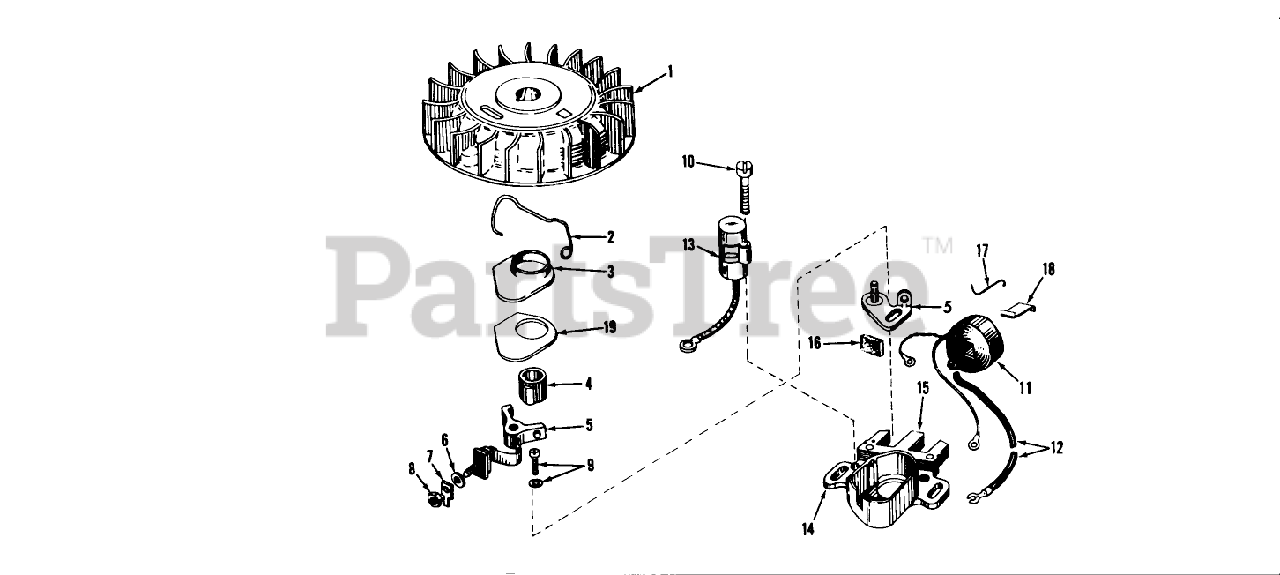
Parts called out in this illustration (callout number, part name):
1	Flywheel
2	Spring Breaker Box
3	Cover, Dust
4	Cam, Breaker
5	Breaker Assy.
6	Washer
7	Terminal
8	DECAL
9	Breaker Screw
10	Condenser Screw
11	Coil Assy., (Inc. Ref. Nos. 12, 13 18)
12	Wire, Lead
13	Condenser
14	Core Plate
15	Stator Assy., (Incl. Nos. 2, 3, 5 thru 14 16 thru 19)
16	Felt,Cam Wiper
17	Clip, Coil
18	Spring Coil Wedge
19	Gasket Dust Cover
